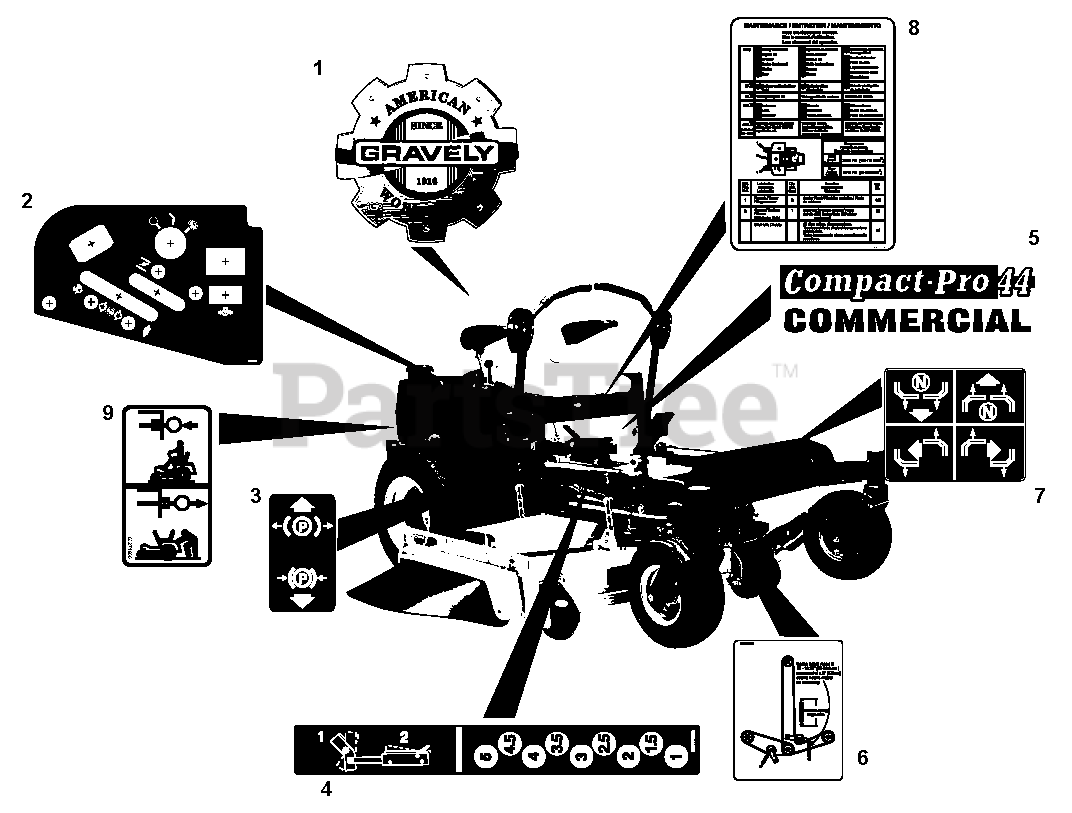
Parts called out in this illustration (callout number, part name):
1	Decal, Gravely Heritage Small
2	Decal, Control Panel
3	Decal, Parking Brake Lever
4	Decal, Height of Cut
5	Decal, Compact-Pro 44
6	Decal, Belt Diagram
7	Decal, Instructional Steering
8	Decal, Maintenance Instructions
9	Decal, Transmission Disconnect
